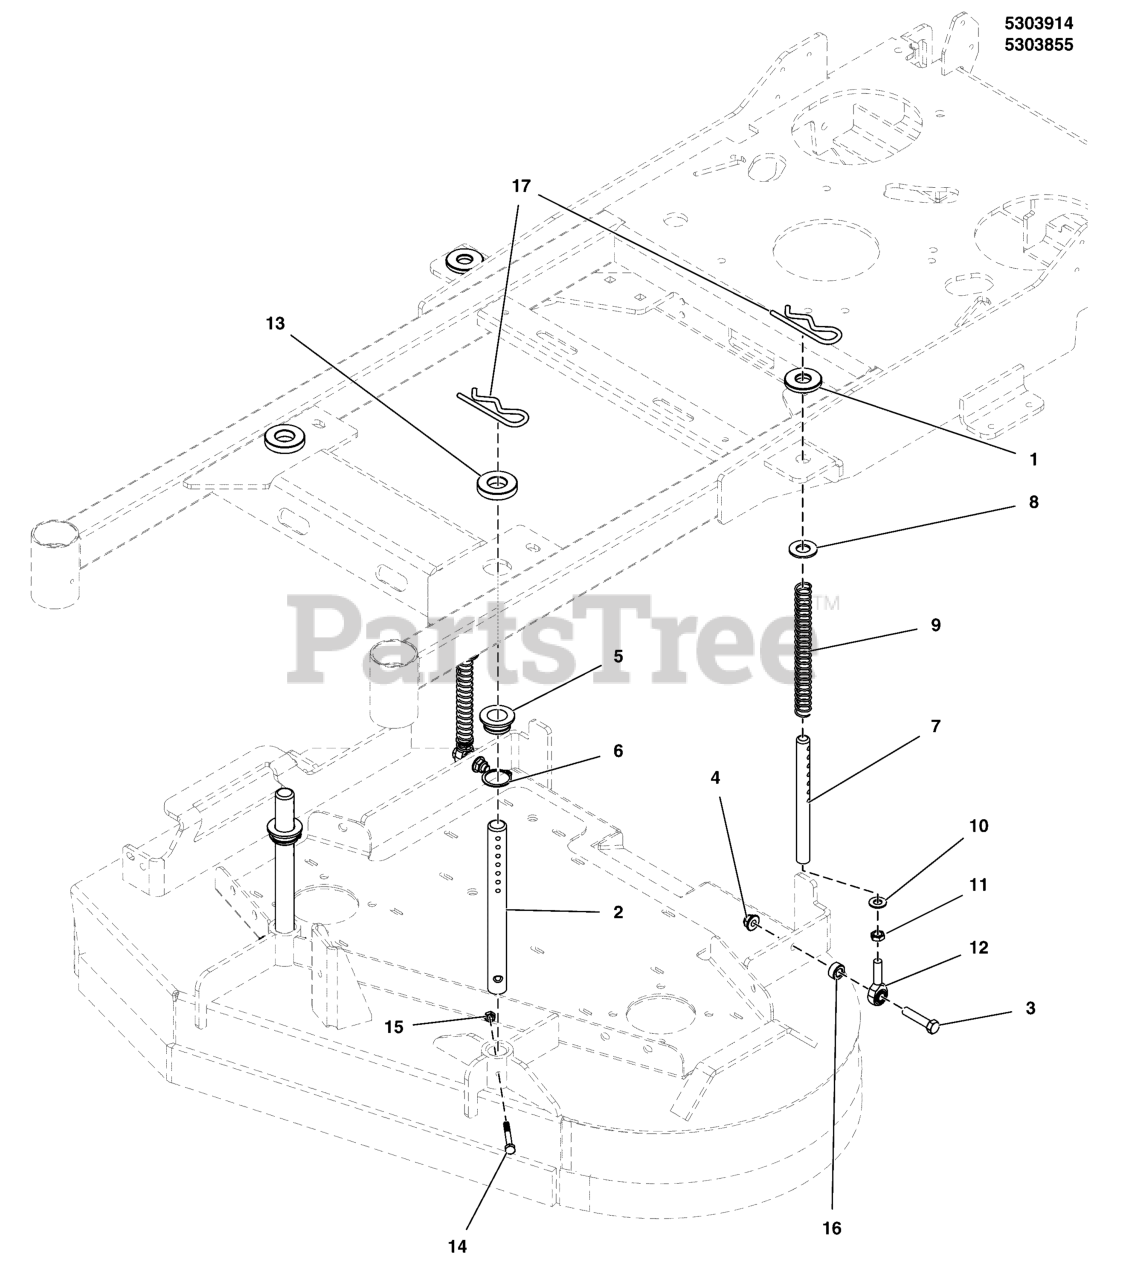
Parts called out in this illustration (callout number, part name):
1	SPACER, .688 X 1.750 X .25, CZ
2	SHAFT, FRONT DECK LIFT, SW25/FW25
3	BOLT, 3/8-16 X 1-3/4" GD5 CZ
4	NUT, 3/8-16 HEX NYLOCK FLANGE
5	BUSHING, FRONT DECK LIFT
6	SNAP RING, EXTERNAL, 1-1/4 SHAFT, BLK
7	SHAFT, REAR DECK LIFT, SW25/FW25
8	WASHER, 5/8 SAE
9	SPRING,COMP,.645IDX8.00LGX.080WR,BLK E-C
10	WASHER, 3/8 SAE
11	NUT, 3/8-24 HEX JAM
12	BALL JOINT, 3/8-24 MALE
13	SPACER, .89 X 1.88 X .38, CZ
14	BOLT, 1/4-20 X 2", GD5
15	NUT, 1/4-20 HEX NYLON LOCK
16	SPACER, .39 X .75 X .38, PM, CZ
17	PIN, HAIR, .1719 X 3-1/4, 7/8 EYE, CZ
